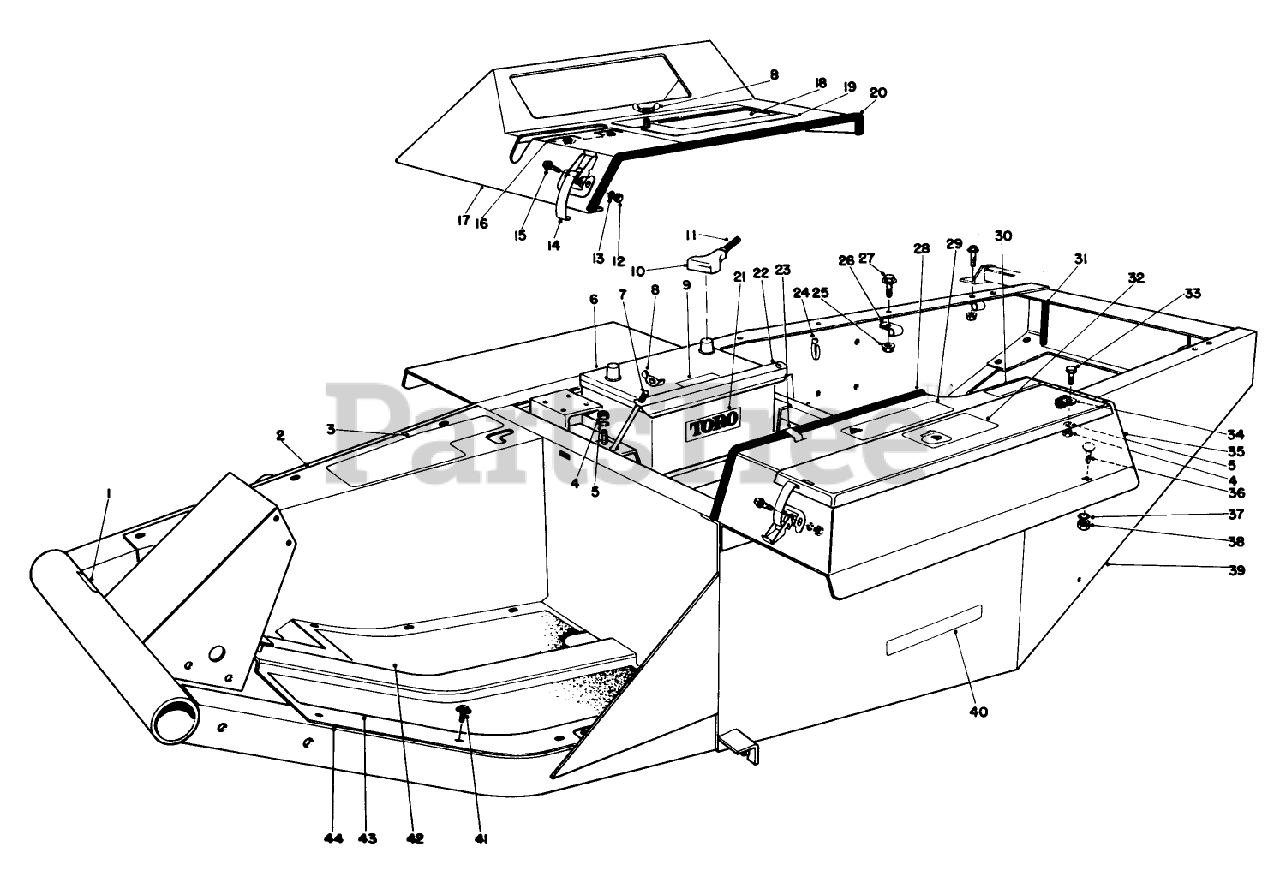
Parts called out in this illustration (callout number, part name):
1	DECAL-PEDAL, TRACTION
2	Footrest
3	Decal Caution
4	NUT-HEX
5	WASHER-LOCK
6	Battery (Incl. Ref. #9 & 21)
7	STUD-HOLDDOWN, BATTERY
8	NUT-WING
9	Decal
10	BOOT-CABLE, BATTERY
11	Cable-Battery Positive (Incl. Ref. #10)
12	NUT-HEX
13	WASHER-LOCK
14	CLAMP-SLOTTED
15	SCREW-SHWH
16	DECAL-PTO
17	Cover-Instrument
18	Decal-Instructions Start.
19	Cover Battery Access
20	TRIM-COVER, INSTRUMENT
21	Decal
22	Battery Hold Down
23	TINNERMAN CLIP
24	TIE-CABLE
25	NUT-HHF, WHIZ
26	CLAMP-R
27	SCREW-HHF
28	TRIM-BOX, TOOL
29	Decal Caution
30	Decal-Diesel Fuel
31	TRIM-FRAME, REAR
32	DECAL-REFUELING
33	SCREW-HH
34	R-CLAMP
35	Box-Tool
36	SCREW-CARR
37	WASHER-LOCK
38	NUT-HEX
39	Frame
40	Decal Torque
41	SCREW-HWH
42	PAD-FLOOR PLATE, RH
43	PAD-PLATE FLOOR, LH
44	Floor Plate
